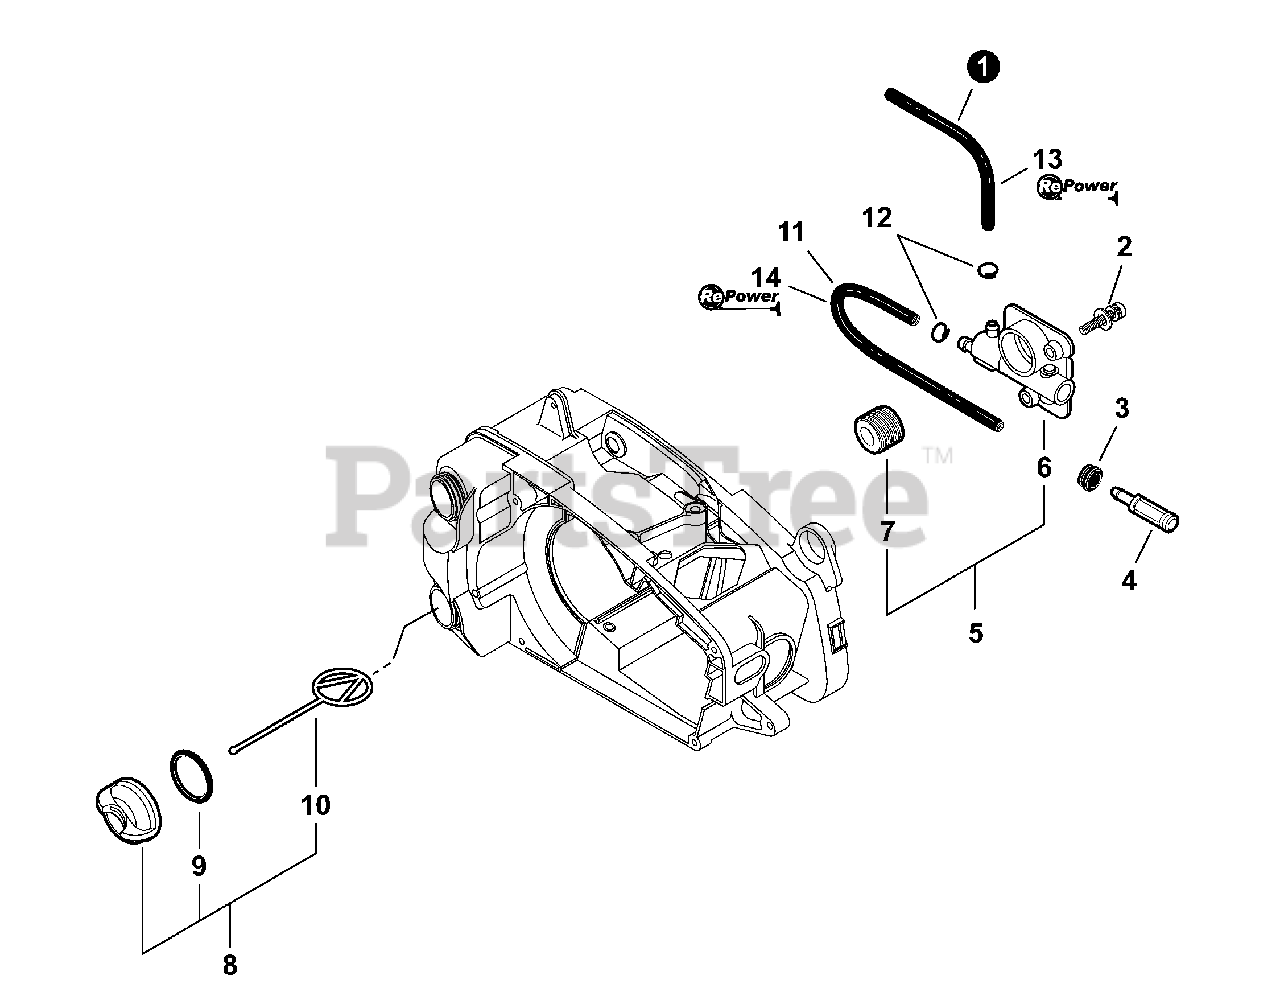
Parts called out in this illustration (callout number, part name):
1	PIPE 3×6×90mm
2	SCREW 4×12
3	GROMMET
4	FILTER, OIL
5	AUTO-OILER KIT
6	AUTO-OILER ASSY
7	GEAR, WORM
8	CAP ASSY, BLACK
9	O-RING 18
10	CONNECTOR, CAP L= 60mm
11	PIPE 3×6×185mm BLACK
12	CLIP 6.5MM
13	PIPE, BULK - REPOWER 3×6mm BLACK
14	PIPE, BULK - REPOWER 3×5mm BLACK
